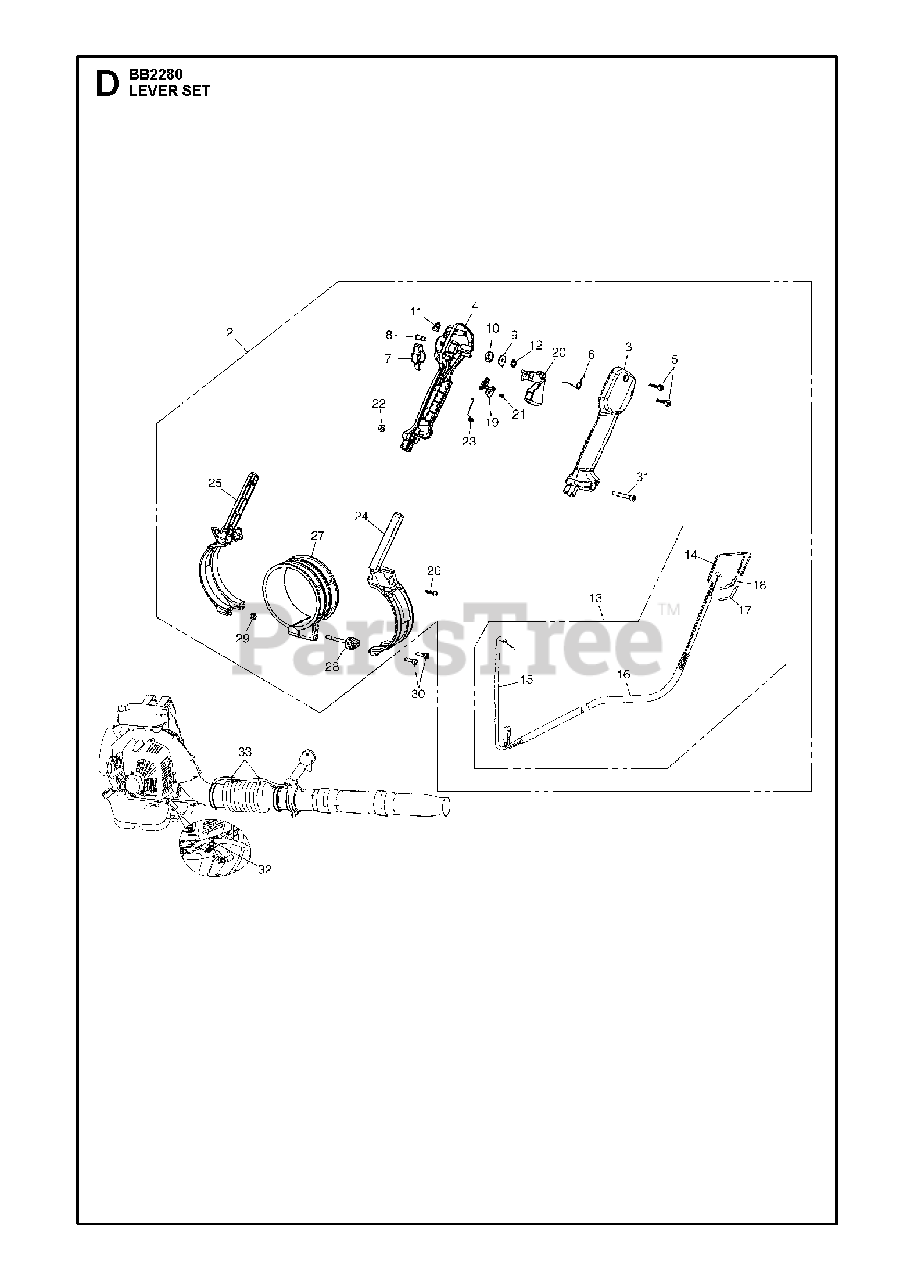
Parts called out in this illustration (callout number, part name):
2	LEVER ASSY
3	HANDLE HALF, RIGHT
4	HANDLE HALF, LEFT
5	SCREW
6	SPRING
7	CONTROL
8	SHAFT PIVOT
9	WASHER
10	SPRING
11	PLATE
12	CLIP
13	WIRING ASSY
14	CORD COMPLETE
15	CABLE, COMP
16	TUBE
17	CONTACT SPRING
18	CONTACT SPRING
19	RETAINER
20	TRIGGER
21	SCREW
22	NUT
23	SPRING
24	HANDLE HOLDER, RIGHT
25	HANDLE HOLDER, LEFT
26	SCREW
27	COLLAR
28	KNOB
29	NUT
30	BOLT
31	SCREW
